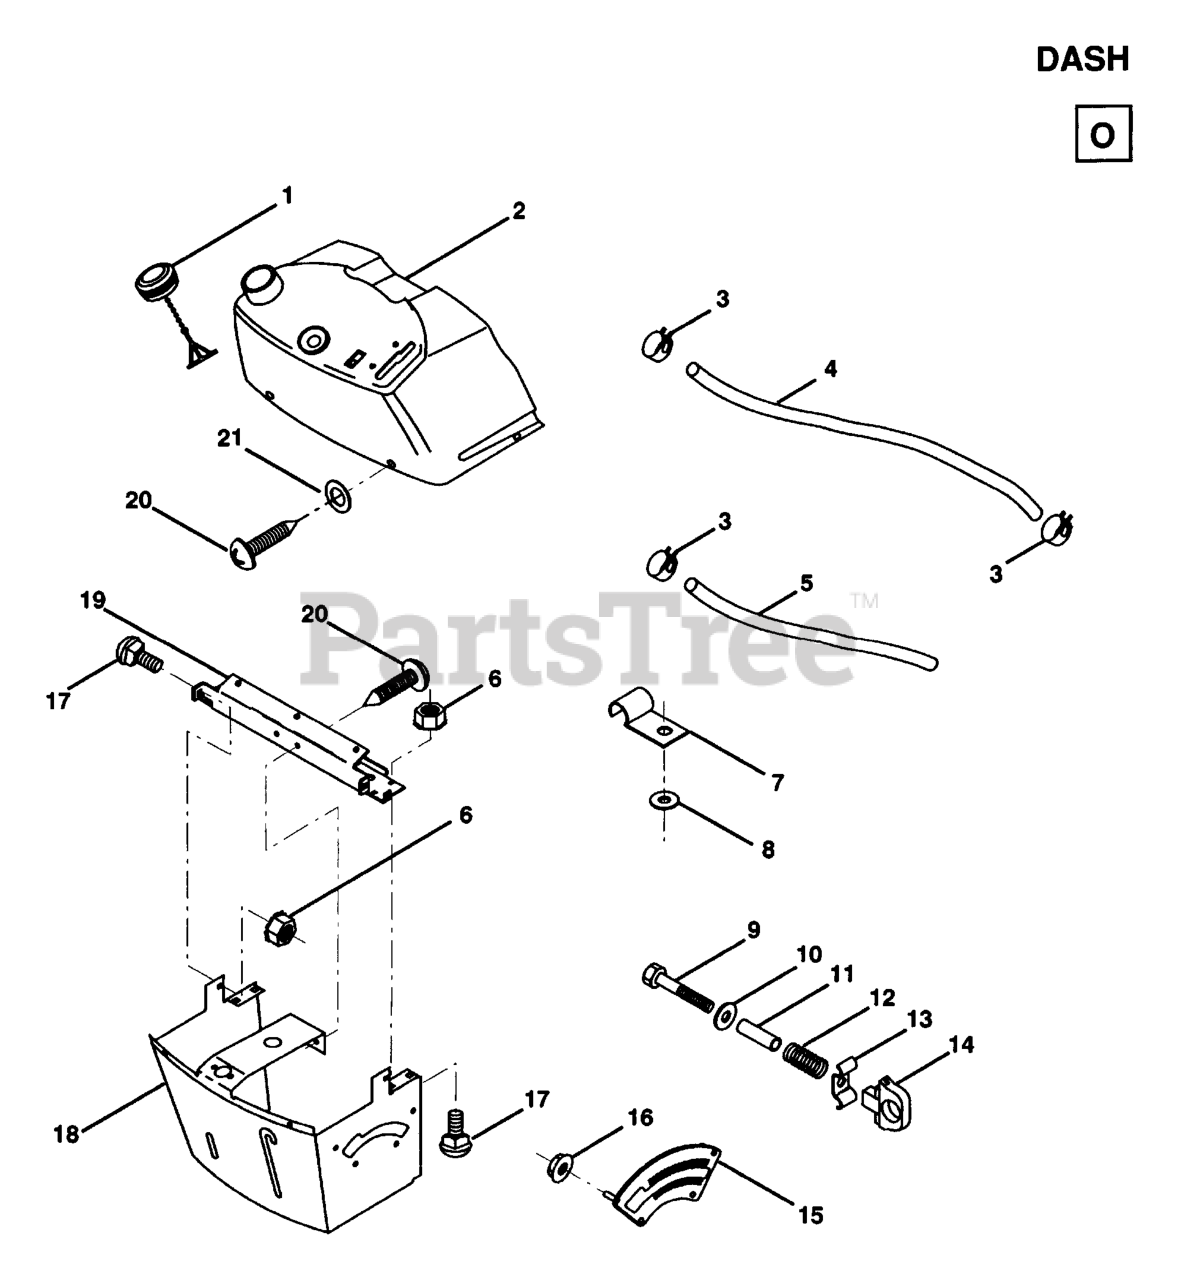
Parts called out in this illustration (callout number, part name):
1	FUEL CAP
2	TANK & DASH ASSY
3	HOSE CLAMP
5	FUEL LINE T
6	NUT.CROWNLOCK.1/4
9	BOLT HEX FIN 1/4-20X1 3/4
10	WASHER
11	SPACER SPLIT
12	SPRING.COMPRESSION
13	KNOB HGT RETAINER
15	ADJUSTER QUAD
16	NUT.PUSH.3/16
18	SUPT ASSY DASH
19	REPL BY 532 13 47-44
20	Screw, Self-Tapping 1/4-20 x 1/2
21	REPL BY 734 11 53-01
